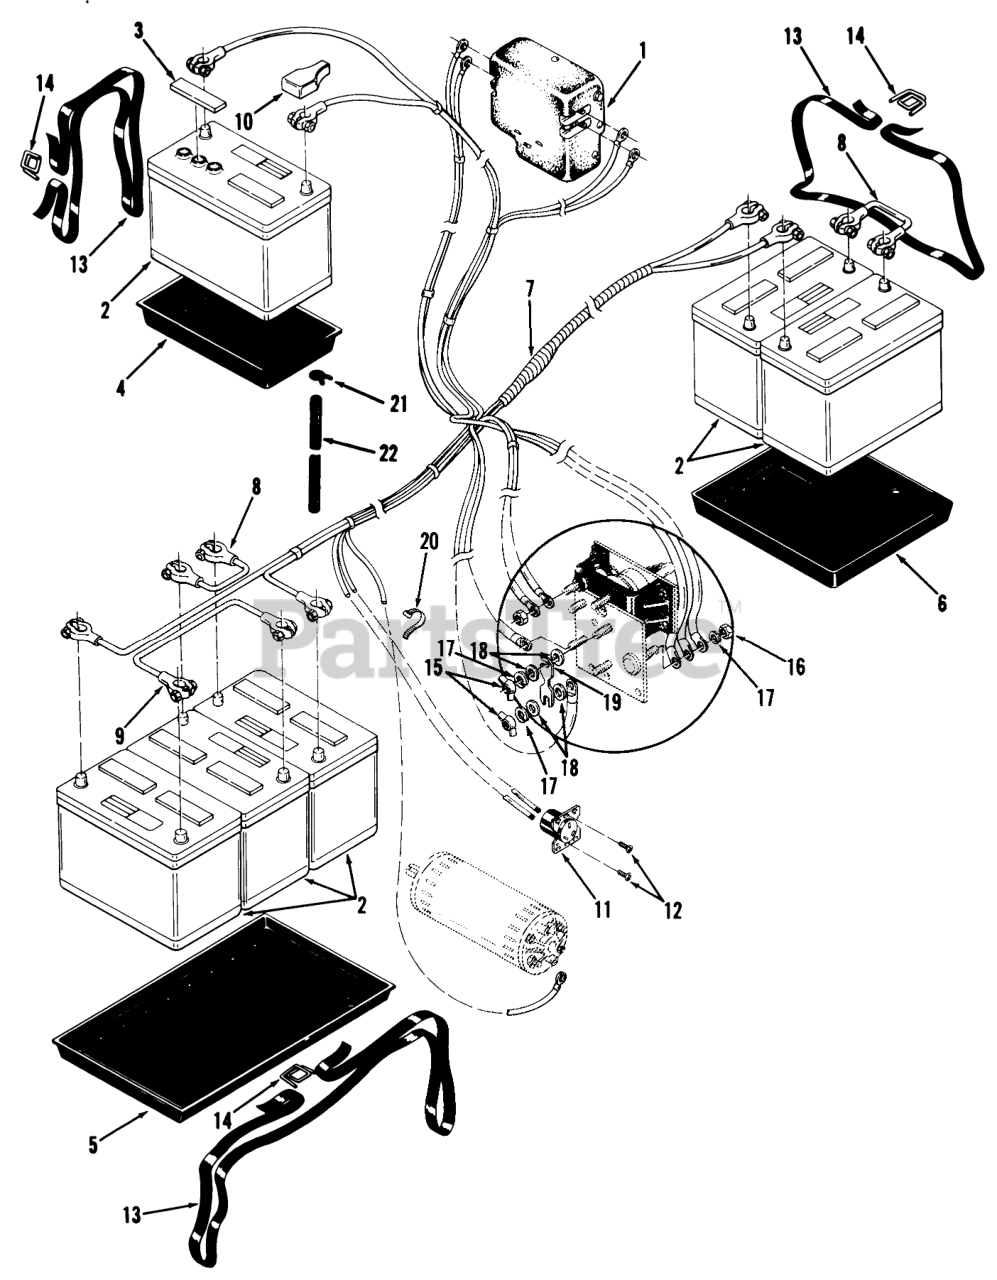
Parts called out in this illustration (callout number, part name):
1	Control Box
2	Battery
3	Battery Cap
4	Battery Tray-Upper
5	TRAY-BATTERY
6	Battery Tray-Rear
7	Wiring Harness-Power Circuit
8	Battery Cable Assembly
9	Battery Cable-Long Jumper
10	Terminal Cover
11	PTO Outlet
12	S.T. Screw #8-32 X 1/2
13	Plastic Banding (17 Ft.)
14	CLIP-STRAP
15	Wing Nut 1/4-20
16	Nut, 1/4-20
17	Washer
18	Washer 1/4
19	FUSE-MAIN (125 AMP)
20	PLASTIC TIE
21	Clamp
22	FUEL HOSE 13" OF 6554
